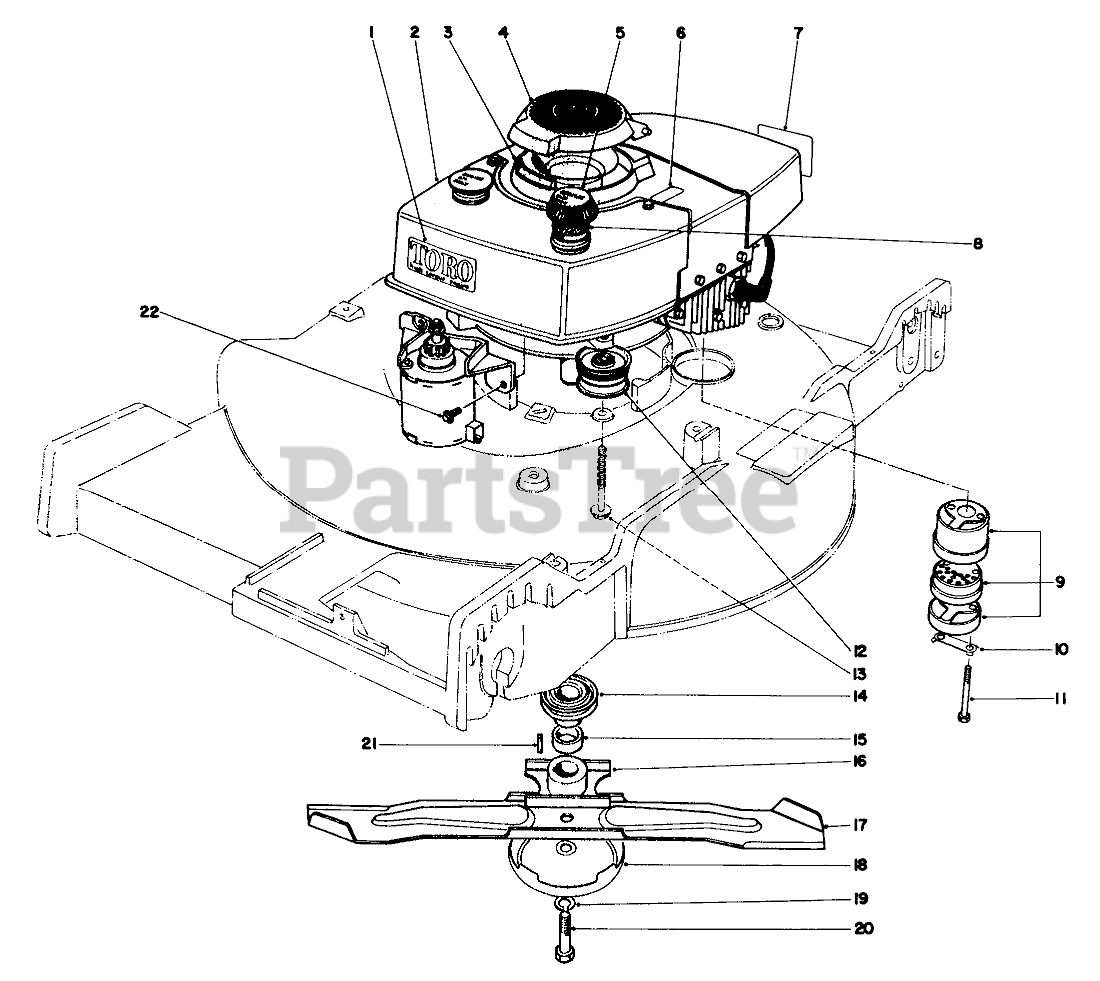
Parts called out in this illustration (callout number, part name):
1	High Torque
2	Engine
3	Base-Hinged
4	Cover-Hinged
5	Gas Cap (Incl. Ref. #8)
6	Decal-Caution
7	Decal Maintenance
8	Gasket
9	MUFFLER ASM
10	CLIP - LOCKING
11	SCREW-HH
12	Idler Pulley
13	3/8-16 X 2-3/4 CAPSCR
14	Pulley
15	Spacer Pulley
16	BLADE RETAINER WA(BLACK)
17	Blade
18	AntiScalp Cup
19	WASHER-LOCK
20	BLADE SCREW
21	Key Square
22	SCREW
